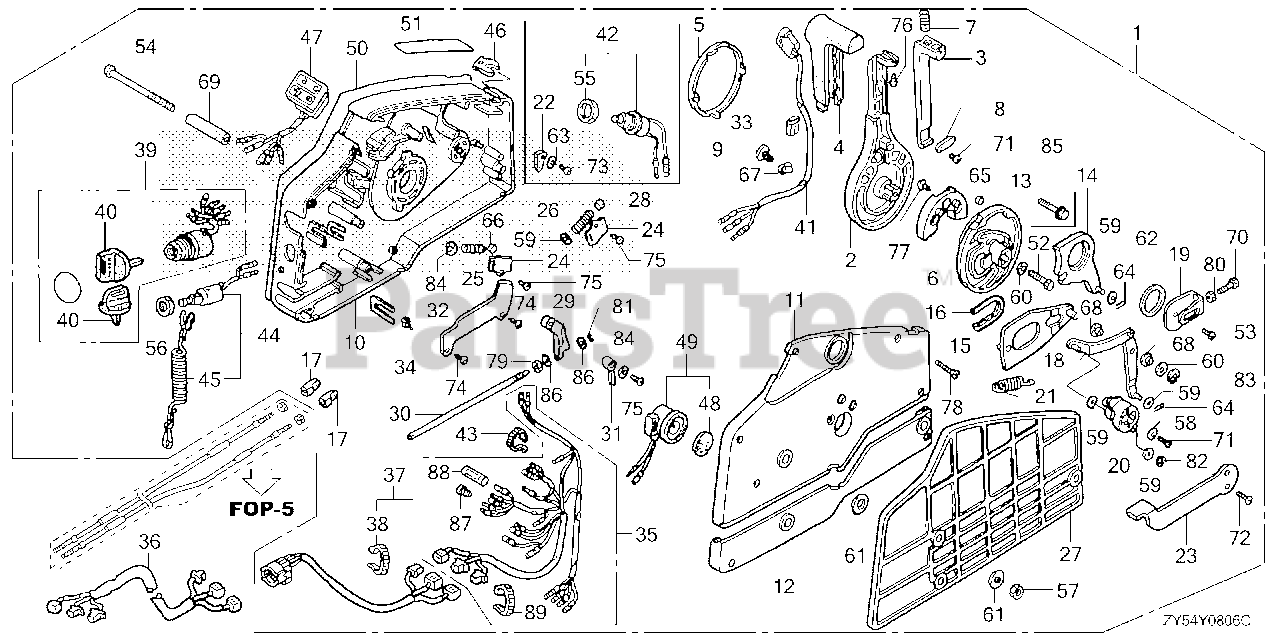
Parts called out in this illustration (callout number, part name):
1	BOX ASSY., REMOTE CONTROL (NHK MEC)
1	BOX ASSY., REMOTE CONTROL (TROLLING CONTROL)(NHK MEC)
2	HANDLE, REMOTE CONTROL
3	LEVER, HANDLE LOCK
4	GRIP, REMOTE CONTROL HANDLE
5	CAP, HANDLE
6	BLOCK, NEUTRAL LOCK
7	SPRING, REMOTE CONTROL HANDLE
8	PLATE, LEVER SETTING
9	CLAMP, HARNESS
10	HOUSING, REMOTE CONTROL BOX (A)
11	HOUSING, REMOTE CONTROL BOX (B)
12	HOUSING, REMOTE CONTROL BOX (C )
13	WHEEL, CONTROL
14	ARM, SHIFT LINK
15	PLATE, SLIDING
16	COLLAR, SLIDING PLATE
17	PIVOT, SHIFT
18	ARM, LINK JOINT
19	BRACKET, LINK JOINT
20	WHEEL, ACCELERATOR
21	SPRING, ACCELERATOR WHEEL
23	LEVER, IDLE
24	PLATE, SPRING SETTING
25	SPRING, SHIFT CLICK
26	SPRING, CHOKE RETURN
27	SPACER, REMOTE CONTROL BOX
28	SPACER, CLICK SPRING
29	BLOCK, THROTTLE FRICTION
30	BOLT, FRICTION
31	SPACER, NEUTRAL SWITCH
32	CLAMP, POWER TILT CORD
33	PIPE, HARNESS GUIDE
34	SPACER, CABLE CLAMP
35	CABLE ASSY., REMOTE CONTROL (B) Use from Frame SN 1300029.
35	CABLE ASSY., REMOTE CONTROL (B) (FOR 4-LED)
36	CABLE ASSY., REMOTE CONTROL EXTENSION Use from Frame SN 1300029.
37	CABLE ASSY., SWITCH PANEL
38	TIE, CABLE (NATURAL 2.4X92) Use up to Frame SN 1300359.
39	SWITCH ASSY., COMBINATION DUAL QTY = (2) (SINGLE)
39	SWITCH ASSY., COMBINATION (SINGLE) (DUAL)
40	KEY ASSY., COMBINATION SWITCH (35100-ZV5-003 ONLY) DUAL QTY = (4) (SINGLE)
41	SWITCH ASSY., POWER TRIM-TILT
43	BAND (BLACK 3.5X140)
44	SWITCH ASSY., EMERGENCY STOP
45	WIRE, EMERGENCY (SINGLE) (DUAL)
46	CLIP, EMERGENCY LOCK
47	LAMP ASSY., INDICATION (2-LED)
47	LAMP ASSY., INDICATION
48	PLATE, TURN SIGNAL BUZZER DUAL QTY = (2) (SINGLE)
49	BUZZER, WARNING DUAL QTY = (2) (SINGLE)
50	PLATE, REMOTE CONTROL (CAUTION=SILVER)
50	PLATE, REMOTE CONTROL (COUTION COLOR=RED & YELLOW)
51	MARK, FAST IDLE
53	SCREW, PAN (6X10)
54	SCREW (6X95)
56	NUT, HEX. (16MM) DUAL QTY = (2) (SINGLE)
57	NUT, HEX. (6MM)
58	WASHER, PLAIN (5MM)
59	WASHER, PLAIN (6MM) Use from Frame SN 4800713.
60	WASHER, PLAIN (8MM) Use from Frame SN 4800713.
61	WASHER (6MM)
62	WASHER (28MM)
64	PIN, LOCK (6MM)
65	PIN (6X6)
66	ROLLER, CLICK
67	CLIP, WIRE HARNESS (6.3MM)
68	COLLAR, LINK JOINT
69	COLLAR, DISTANCE (6X10X43.5)
70	BOLT, HEX. (5X16)
71	SCREW, PAN (5X10)
72	SCREW, FLAT (5X12) Use from Frame SN 4800713.
74	SCREW, TAPPING (5X8) (FOR SILVER MUFFLER)
75	SCREW, TAPPING (5X10)
76	SCREW, TAPPING (5X12)
77	SCREW, TAPPING (6X16)
78	SCREW, TAPPING (5X25)
79	NUT, HEX. (6MM)
80	NUT, HEX. (5MM)
81	E-RING (3MM)
82	E-RING (4MM)
83	E-RING (7MM)
84	WASHER, PLAIN (5MM)
85	BOLT, FLANGE (8X35) Use from Frame SN 4800713.
86	WASHER, PLAIN (4MM) Use from Frame SN 4800713.
87	PLUG, CONNECTOR (INNER) (TROLLING CONTROL)
88	PLUG, CONNECTOR (OUTER) (ENGINE NO.)
89	TIE, CABLE (NATURAL 2.4X92) Use up to Frame SN 1300359.
